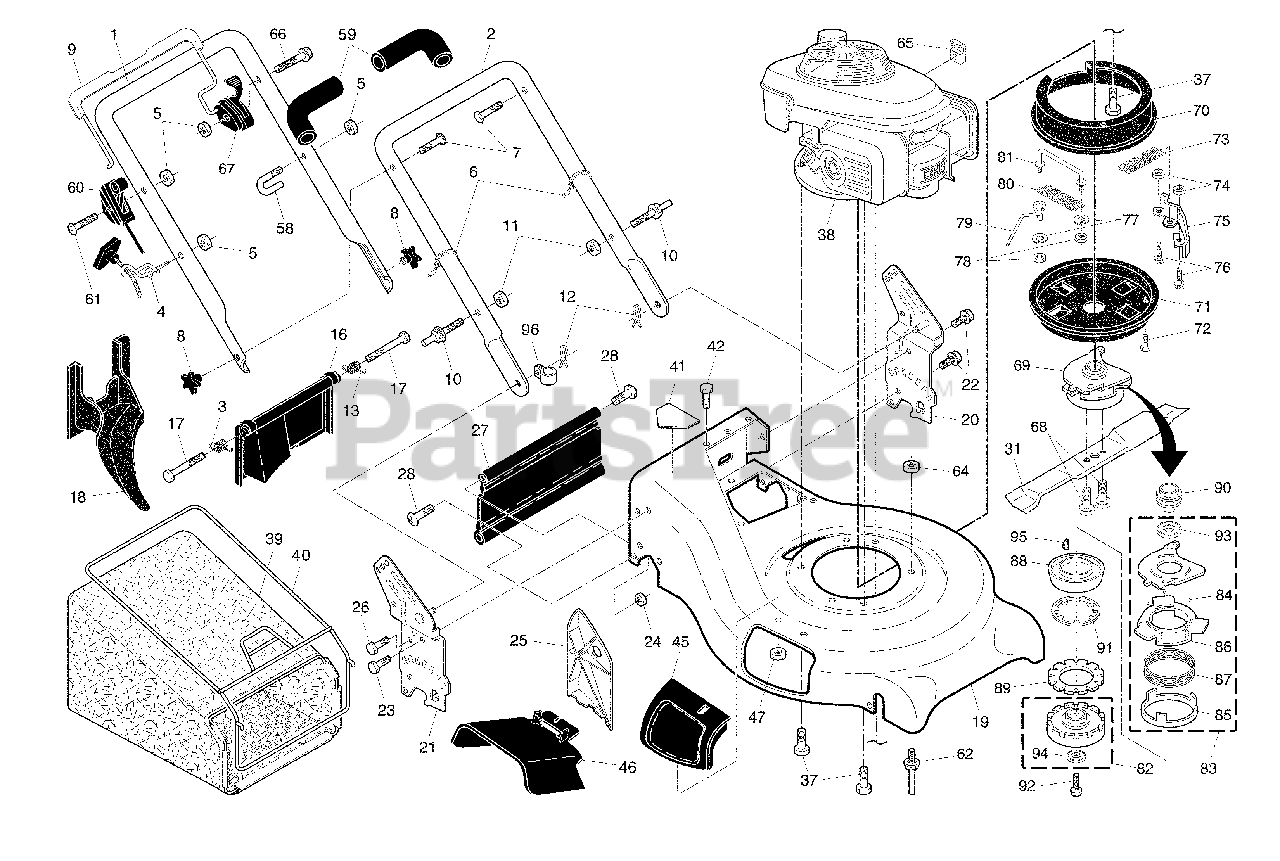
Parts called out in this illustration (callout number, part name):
1	Handle, Upper
2	Handle, Lower
3	Spring, Rear Door, RH
4	Guide, Rope, Side
5	Nut, Hex Lockwasher Insert 1/4-20
6	Wire, Tie
7	Bolt, Handle 5/16-18 x 1.75
8	Knob, Handle
9	Bar, Control, Auto-Walk
10	Bolt, Carriage
11	Nut, Hex, Centerlock 5/16-18 UNC
12	Cotter, Hairpin
13	Spring, Rear Door, LH
16	Rear Door Assembly
17	Bolt, Rear Door
18	Plug, Mulcher
19	Kit, Housing
20	Handle Bracket Assembly, LH
21	Handle Bracket Assembly, RH
22	Screw, Hex Washer Head
23	Bolt, Hex Head 5/16-18 x 5/8
24	Nut, Hex, with Lock Washer Insert 5/16-18
25	Baffle, Side
26	Screw 12 x 5/8
27	Skirt, Rear
28	Screw, Hinge 1/4-20 x 1.25
31	Blade, 21"
37	Bolt, Engine
39	Grassbag
40	Frame, Grassbag
41	Danger Decal
45	Mulcher Door Assembly
46	Deflector, Discharge
59	Grip, Handle, Foam, Smooth
60	Throttle / Engine Control
61	Screw, Hex Head 1/4-20 x 2-1/8
62	Belt Guide, Stud
64	Nut, Hex 3/8-16
65	Bracket, Throttle
66	Screw, Hex Washer Head 1/4-20 x 1/2
67	Blade Brake / Clutch Control
68	Bolt, Hex Head
69	Blade Brake / Clutch
70	Belt Cover, Upper
71	Belt Cover, Lower
72	Screw, Tapping, Hex Washer Head #10-24
74	Nut, Hex, Centerlock, Zinc Plated 1/4-20
75	Bracket
76	Bolt, Hex Cap Head 1/4-20 x 5/8
77	Washer, Flat
78	Nut, Hex 3/8-16
79	Belt Keeper
81	Link, Torque
82	Holder Assembly, Blade
83	Plate Assembly, Ball Control
84	Ball, Steel
85	Plate, Spring Hook
86	Plate, Brake
87	Spring, Ball Plate
88	Disk, Drive
89	Disk, Driven
90	Pulley, Drive
91	Spring, Clutch
92	Bolt, Flange (10 x 24)
93	Bearing, Radial Ball (6006)
94	Bearing, Radial Ball (6204)
95	Key, Woodruff (16 x 15)
96	Clip, Cable
